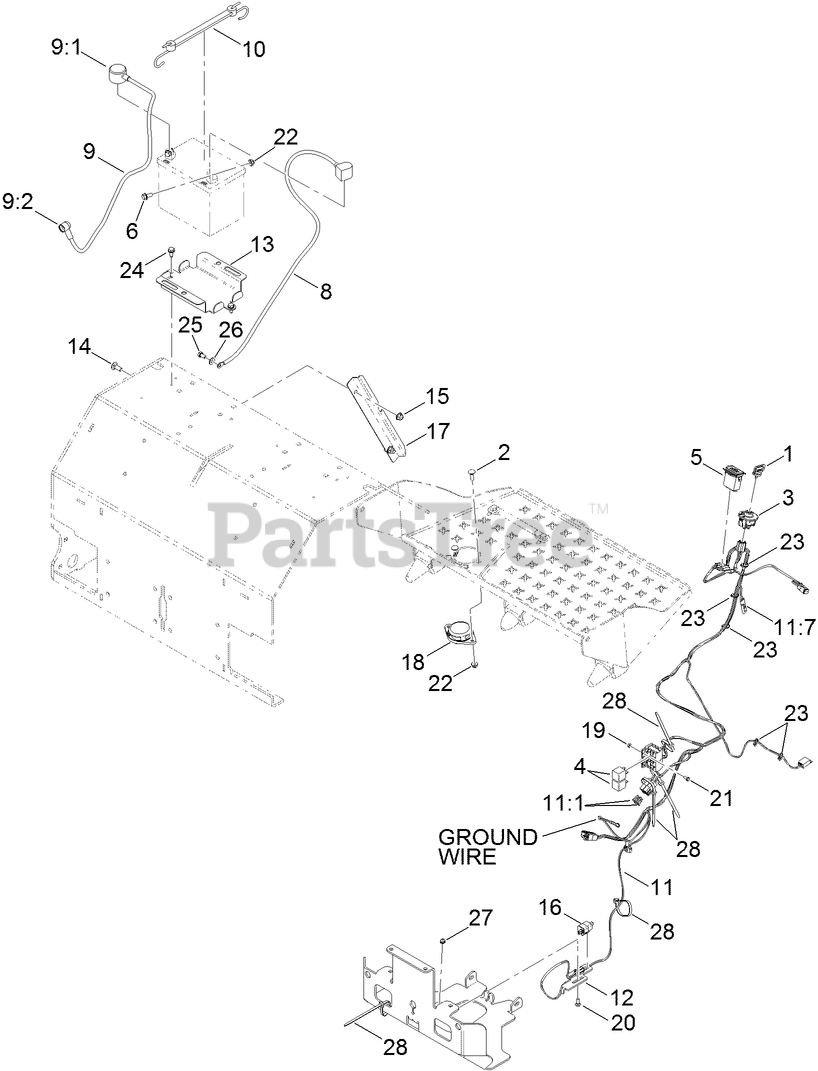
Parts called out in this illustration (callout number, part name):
1	KEYS-IGNITION (SPARE PAIR)
1	KEY-IGNITION
2	BOLT-CARR
3	SWITCH-IGNITION
5	METER-HOUR
6	SCREW-HHF
8	CABLE-BATTERY, BLACK
9	POSITIVE BATTERY CABLE ASM
9:1	INSULATOR-BATTERY
9:2	INSULATOR-SOLENOID
10	HOLDDOWN-BATTERY
11	HARNESS ASM
11:1	FUSE-BLADE TYPE, 20 AMP
11:7	CAP-PLUG
12	MOUNT-SWITCH
13	BRACKET-BATTERY
14	BOLT-CARR
15	NUT-HF, NI
16	SWITCH
17	GUARD-HARNESS
18	SWITCH-SEAT
19	NUT-LOCK, NI
20	BOLT-CARR
21	SCREW-HWH
22	NUT-HF, NI
23	TIE-CABLE
24	SCREW-HWHTF
25	SCREW-HH
26	WASHER-PLAIN
27	NUT-HF
28	TIE-PLASTIC
